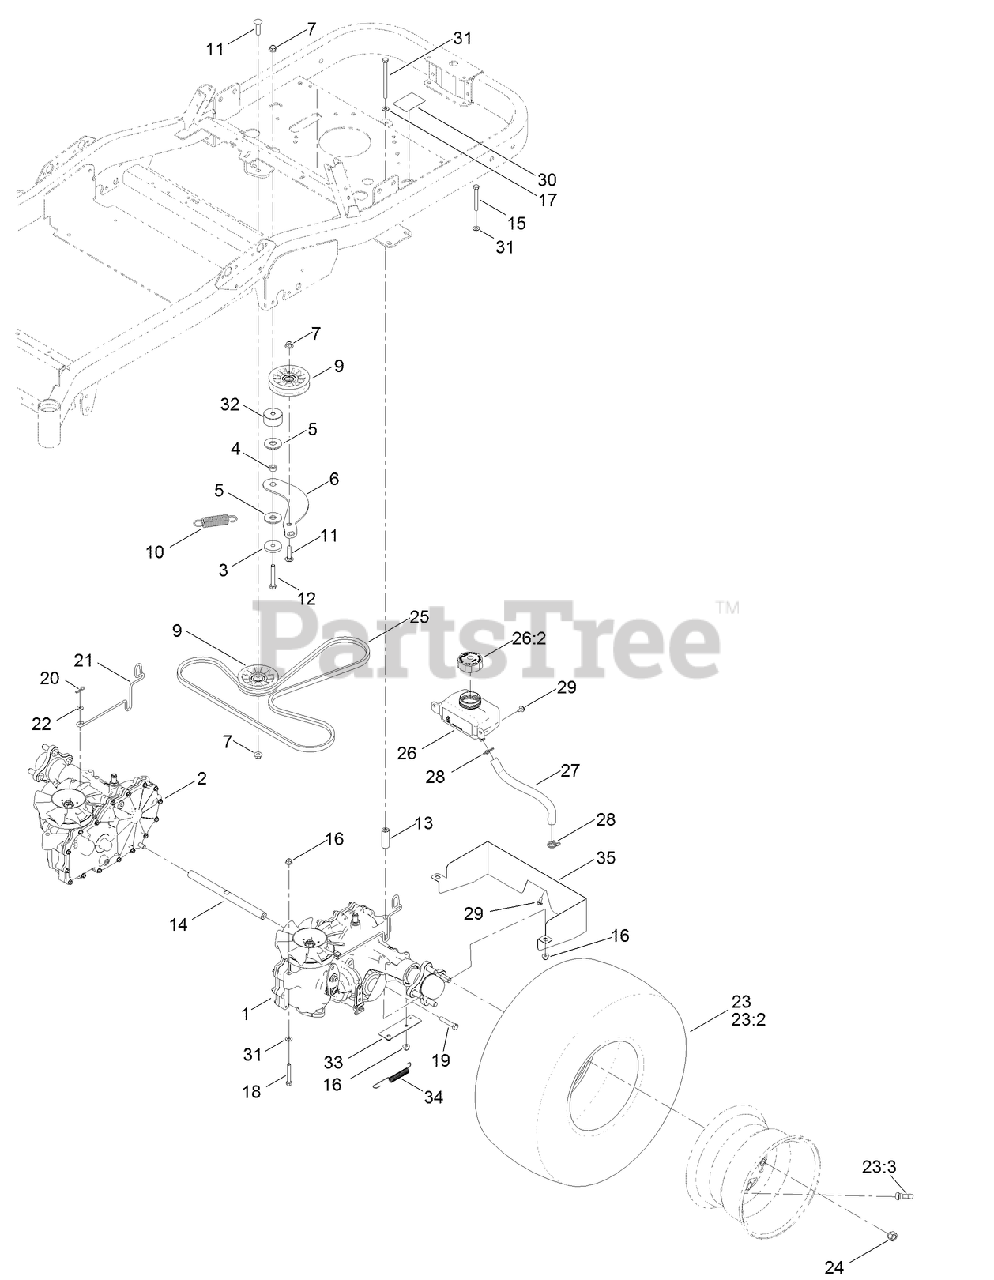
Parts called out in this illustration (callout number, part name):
1	LH HYDRO TRANSMISSION ASM
2	RH HYDRO TRANSMISSION ASM
3	WASHER-PLAIN
4	SPACER
5	WASHER-FRICTION, COMPOSITE
6	ARM-IDLER
7	NUT-HF, NI
9	PULLEY-IDLER, FLAT
10	SPRING-EXTENSION
11	SCREW-CARR
12	SCREW-HH
13	SPACER-HYDRO
14	SHAFT-CROSS, HYDRO
15	SCREW-HH
16	NUT-HF, NI
17	SCREW-HH
18	SCREW-HH
19	SCREW-HH
20	PIN-COTTER
21	ROD-BYPASS
22	WASHER
23	TIRE AND WHEEL ASM
24	NUT-LUG
25	V-BELT
26	HYD RESERVIOR ASM
26:2	CAP-RESERVOIR, HYD
27	HOSE-OVERFLOW
28	CLAMP-HOSE
29	SCREW-HHFTF
30	DECAL-BYPASS
31	WASHER-PLAIN
32	SPACER
33	PLATE-SPRING
34	SPRING-EXTENSION
35	GUARD, REAR
